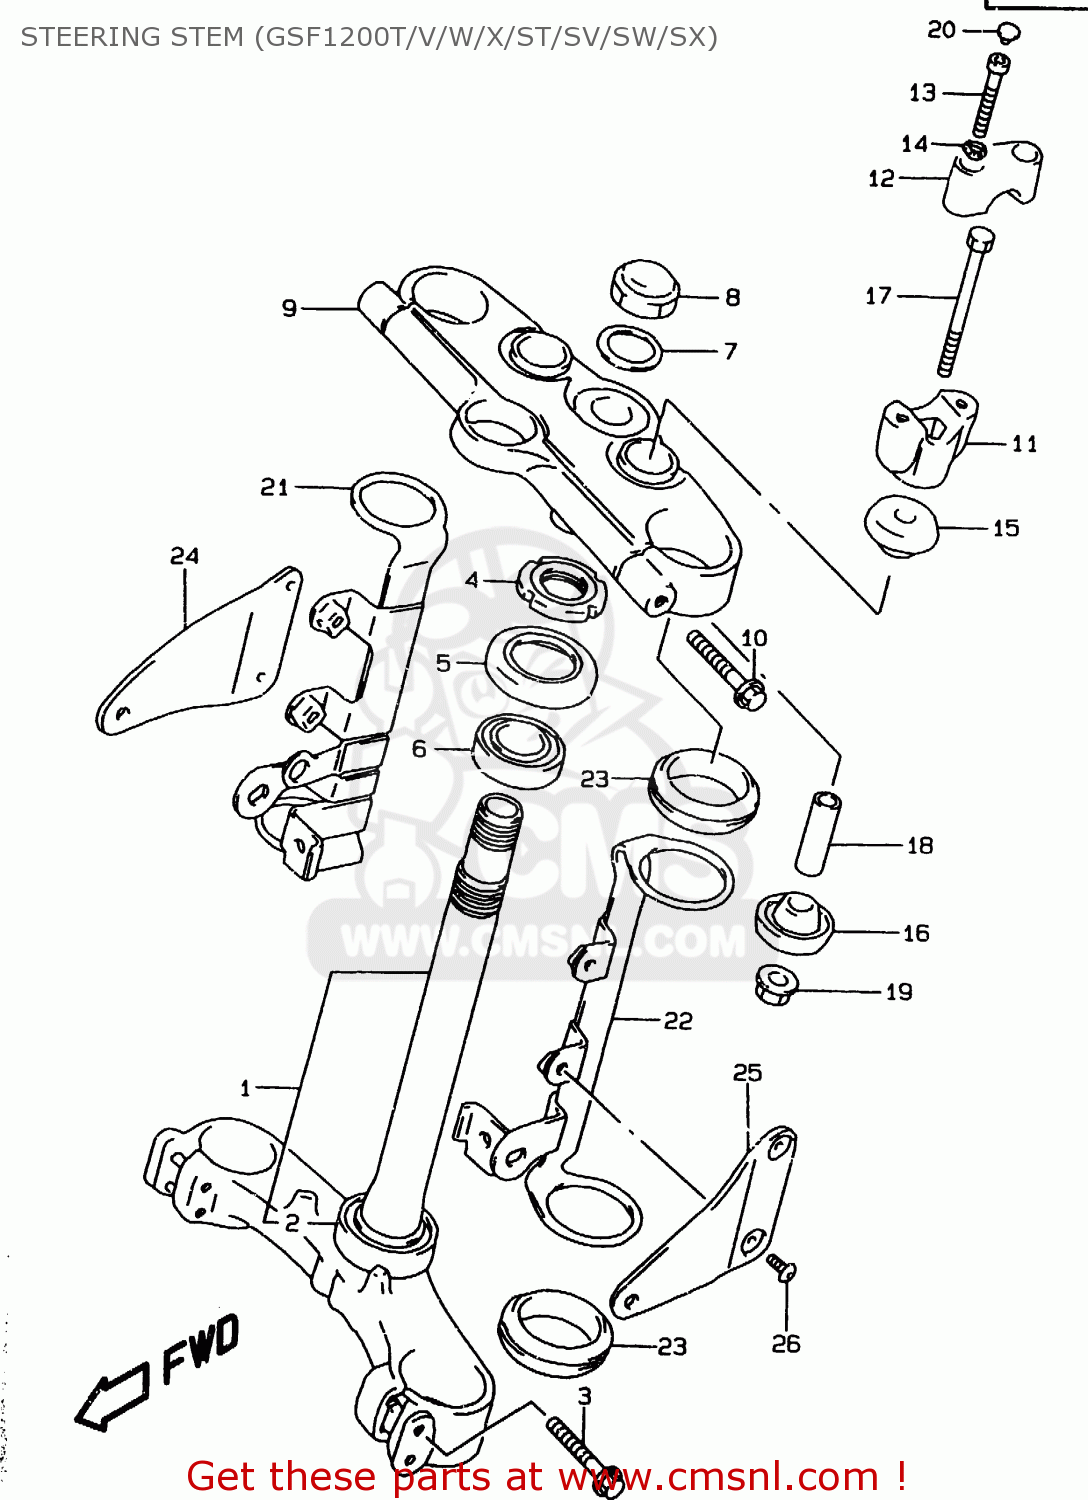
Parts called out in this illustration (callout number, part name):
1	STEM,STEERING
2	BEARING(30X55X17)
3	BOLT
4	NUT,STEERING STEM(25X44X10)
5	SEAL,STEERING UPR DUST
6	BEARING(25X47X15)
7	WASHER(22.5X32X1.6)
8	NUT,CAP
9	HEAD,STEERING STEM
10	BOLT
11	HOLDER,HANDLE UNDER
12	HOLDER,HANDLE UPR
13	BOLT
14	WASHER
15	CUSHION,RUBBER UPR
16	CUSHION,RUBBER UNDER
17	BOLT,HANDLE HOLDER(10X70)
18	SPACER
19	NUT
20	CAP(OD:11)
21	BRACKET,HEADLAMP HOUSING,R
22	BRACKET,HEADLAMP HOUSING,L
23	DAMPER,HEADLAMP HSG BRACKET
24	STAY,HEADLAMP HOUSING,R
25	STAY,HEADLAMP HOUSING,L
26	SCREW(6X12)
